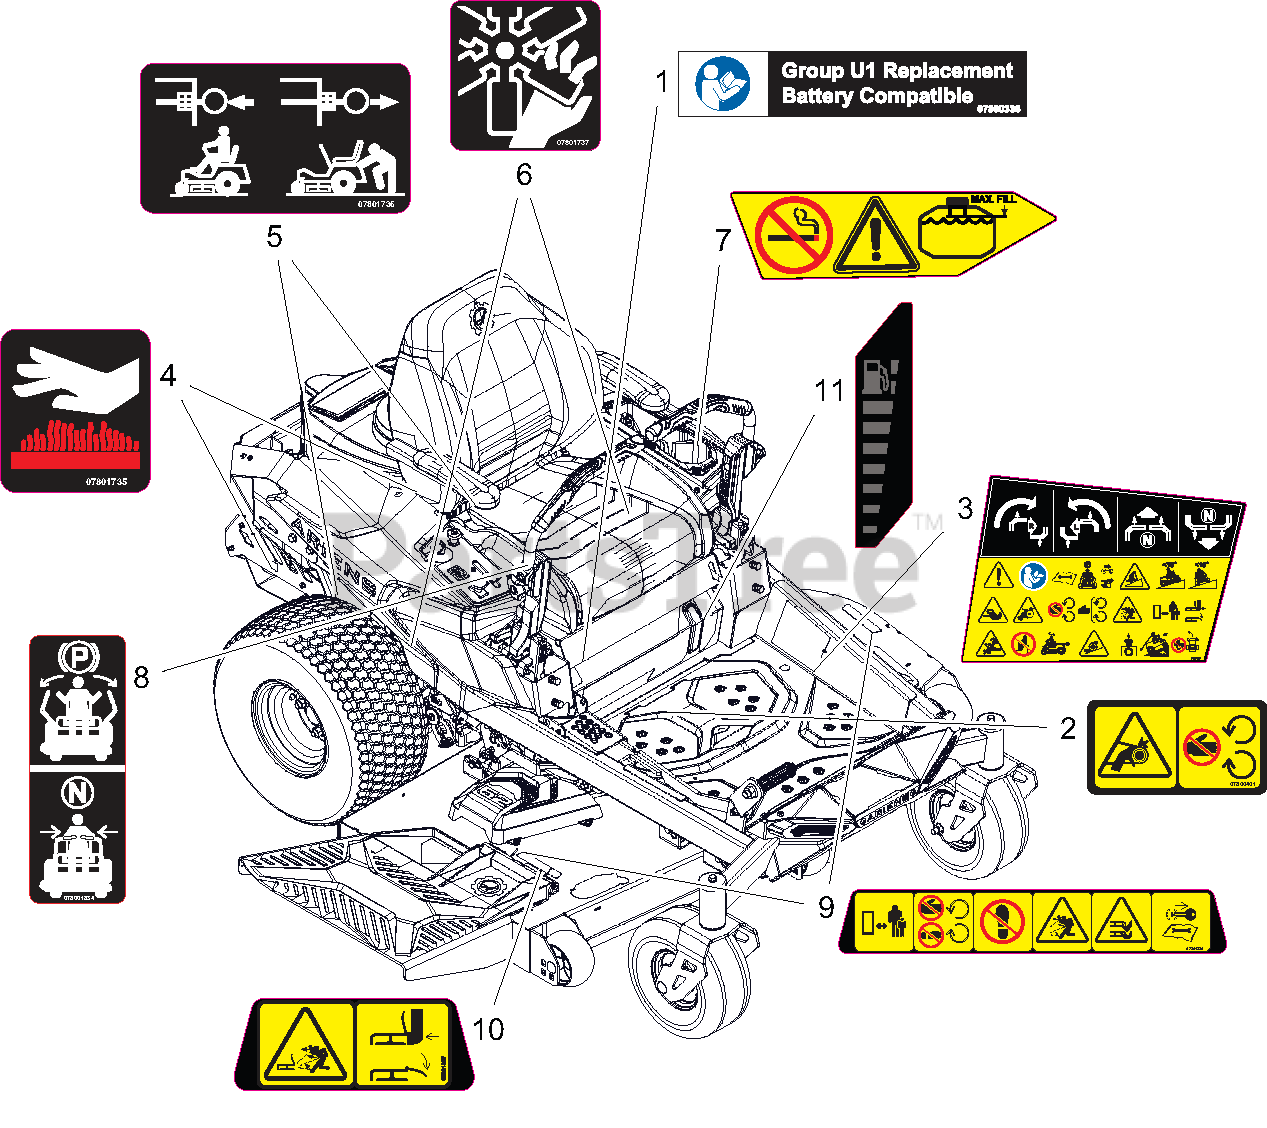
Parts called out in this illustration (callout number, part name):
1	DECAL, U1 BATTERY REPLACEMENT
2	DECAL, SAFETY - GUARDING
3	DECAL- MAIN SAFETY-INSTRUCTION
4	DECAL- HOT SURFACE
5	DECAL- TRANSAXLE DISCONNECT
6	DECAL- DANGER FAN
7	DECAL- FUEL WARNING
8	DECAL- STEERING-BRAKE
9	DECAL- SAFETY - MOWER DECK
10	DECAL- SAFETY - DECK GUARDING
11	DECAL, FUEL LEVEL
